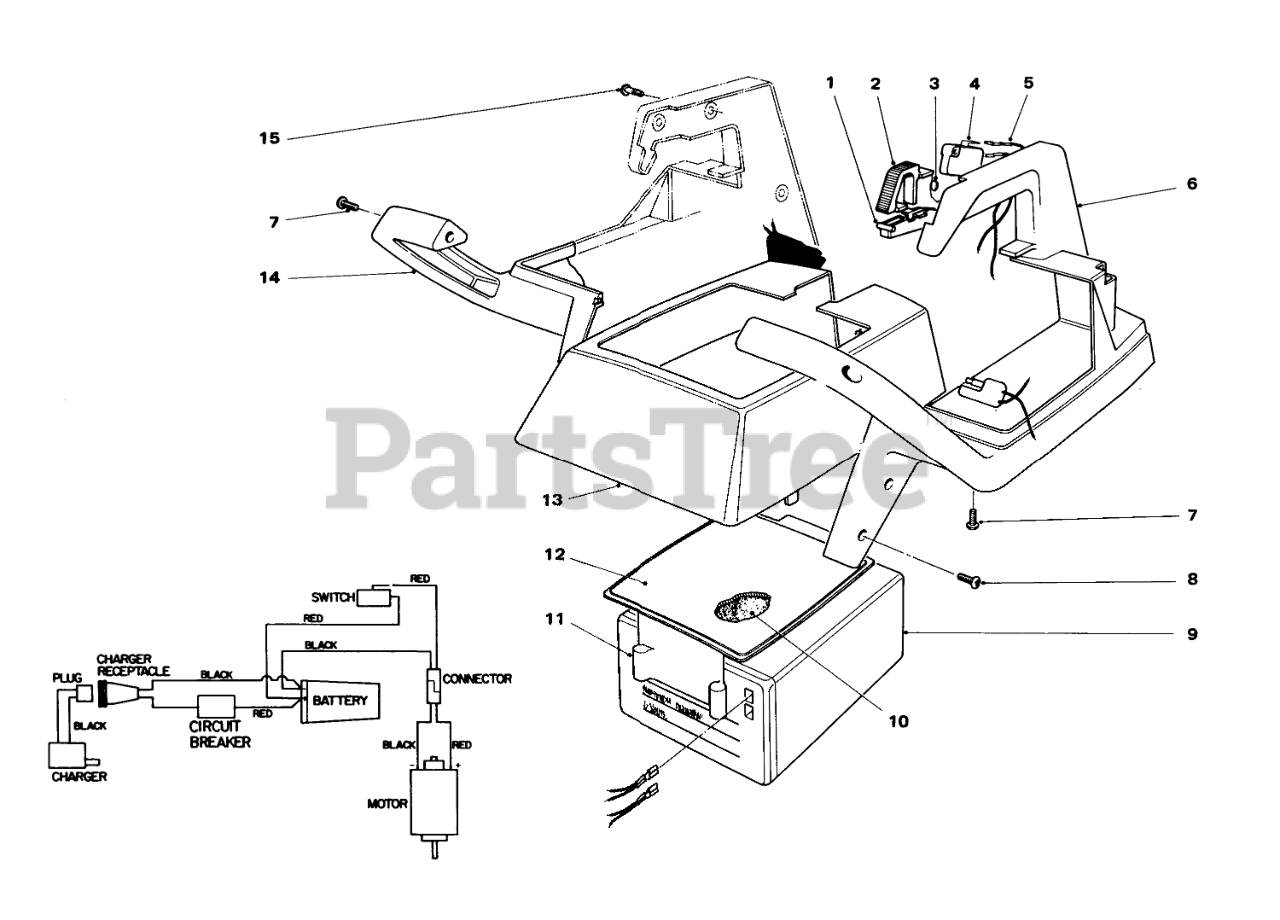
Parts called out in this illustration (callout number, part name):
1	TRIGGER
2	TRIGGER LOCK
3	SPRING
4	Switch
5	Wiring Harness
6	Left Hand Case
7	Screw
8	10-16 X .31 SCREW
9	BATTERY
10	FOAM PAD
11	CONTROL PANEL, CL-710
12	DECAL - CONTROL PANEL
13	Cover
14	Right Hand Case
15	SCREW-PPH
